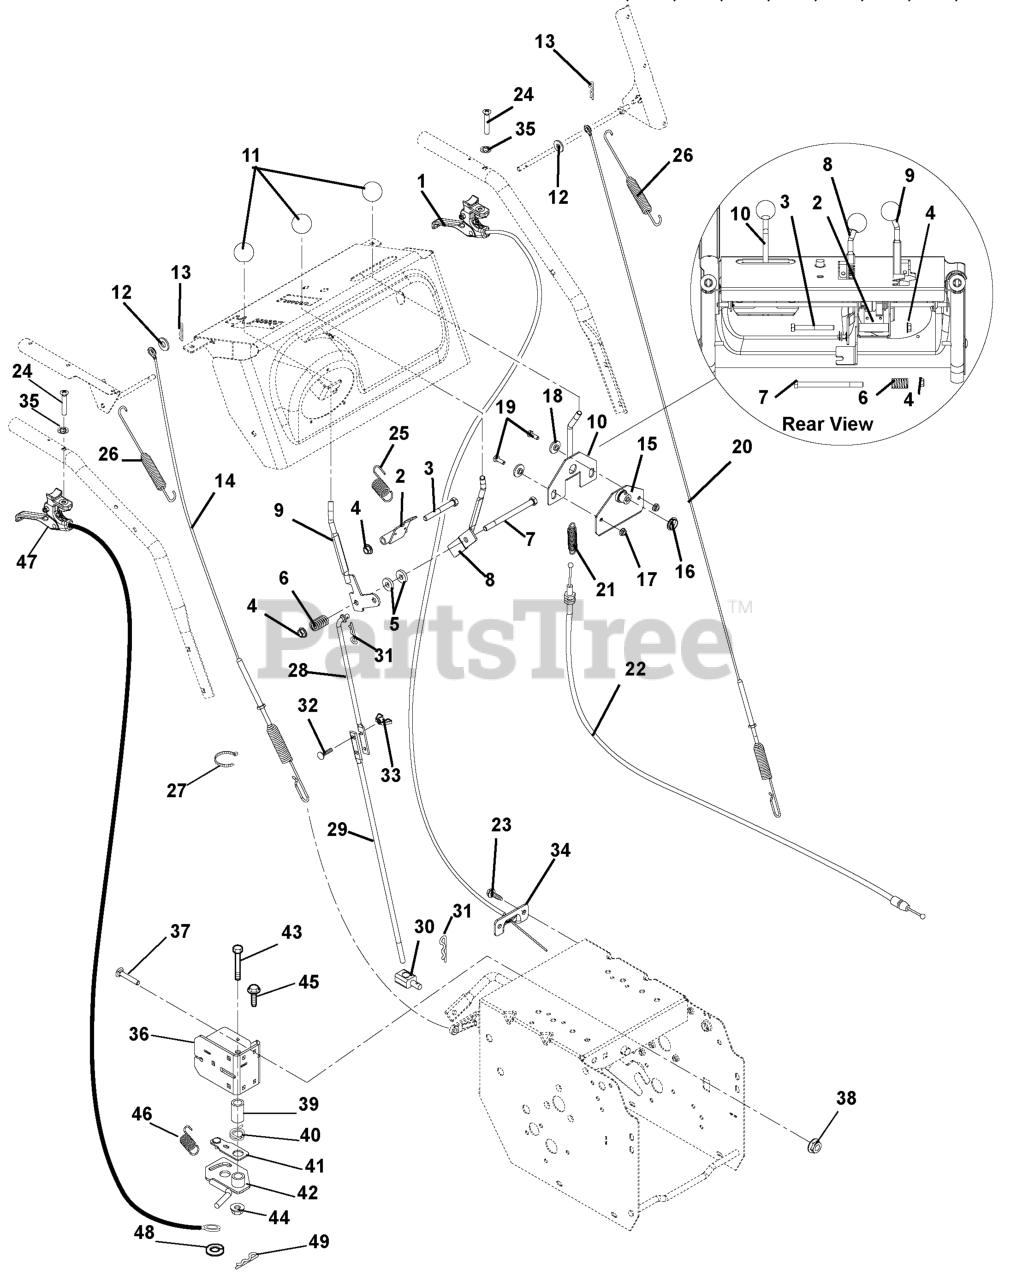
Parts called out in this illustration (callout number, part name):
1	CABLE-TRIGGER-REMOTE WHEEL-DEL
2	ARM, INTERLOCK
3	@BLT-HEX .38-16X3.00 GR5 YWZC
4	@NUT-LK-TOP-FLG .38-16 YWZC
5	WSHR-FL-STL .406X1.00X.188 YWZ
6	SG-COMP .125X.781X1.250
7	@BLT-HEX .38-16X5.00 GR5 YWZC
8	CONTROL, DEFLECTOR
9	LEVER, SHIFT
10	LEVER, CHUTE CONTROL
11	KNOB,BALL -BLACK 1.47" .375-16
12	@WSHR-FL-STL.281X.62X.065 YWZC
13	PIN-HAIR INT .06X.18X.77
14	CABLE, ATTACHMENT
15	MOUNT, CHUTE CONTROL
16	BUSHING, POLYLINER-.75 SNAPIN
17	@NUT-LK-TOP-FLG .25-20 YWZC
18	BSHG-FLG .265X.448X.243X1.00
19	@BLT-HEX .25-20X.75 GR5 YWZC
20	CABLE, TRACTION - DELUXE
21	SG-TENS .048X.44X1.75 WLD 9
22	CABLE, CHUTE LOCK
23	SCR-TAP .25-20X.50 HWH TR YWZ
24	SCR-MCH .25-20X1.50 OVAL HD
25	SPRING-EXT .047X.438X1.45
26	SG-TENS .056X.60X4.40
27	CABLE TIE LG 5-1/2
28	ROD, SHIFT-UPPER
29	ROD, SHIFT-LOWER
30	PIVOT,SHIFT ROD .375-16(TRUNN)
31	PIN-HAIR, ENDRIES #25 YWZC
32	@BLT-RDHDSQNK .25-20X.75 G5YZ
33	NUT-LK WING .250-20 YWZC
34	BRACKET, CABLE MOUNT
35	WSHR-LK-INT .250 TH TYA
36	BRACKET, HEIGHT ADJUSTER
37	@BLT-RDHDSQNK .25-20X.75 G5YZ
38	@NUT-LK-TOP-FLG .25-20 YWZC
39	BSHG-SLV .385X.500X1.045
40	SG-TORS .067X.88
41	ARM, OVERTRAVEL
42	LOCK, HEIGHT ADJUSTER
43	@BLT-HEX .38-16X1.75 GR5 YWZC
44	@NUT-LK-TOP-FLG .38-16 YWZC
45	SCR-TAP .25-20X.50 HWH TR YWZ
46	SPRING-EXT .047 X .438 X 1.85
47	CABLE, TRACK REMOTE
48	@WSHR-FL-STL.281X.62X.065 YWZC
49	PIN-HAIR INT .06X.18X.77
